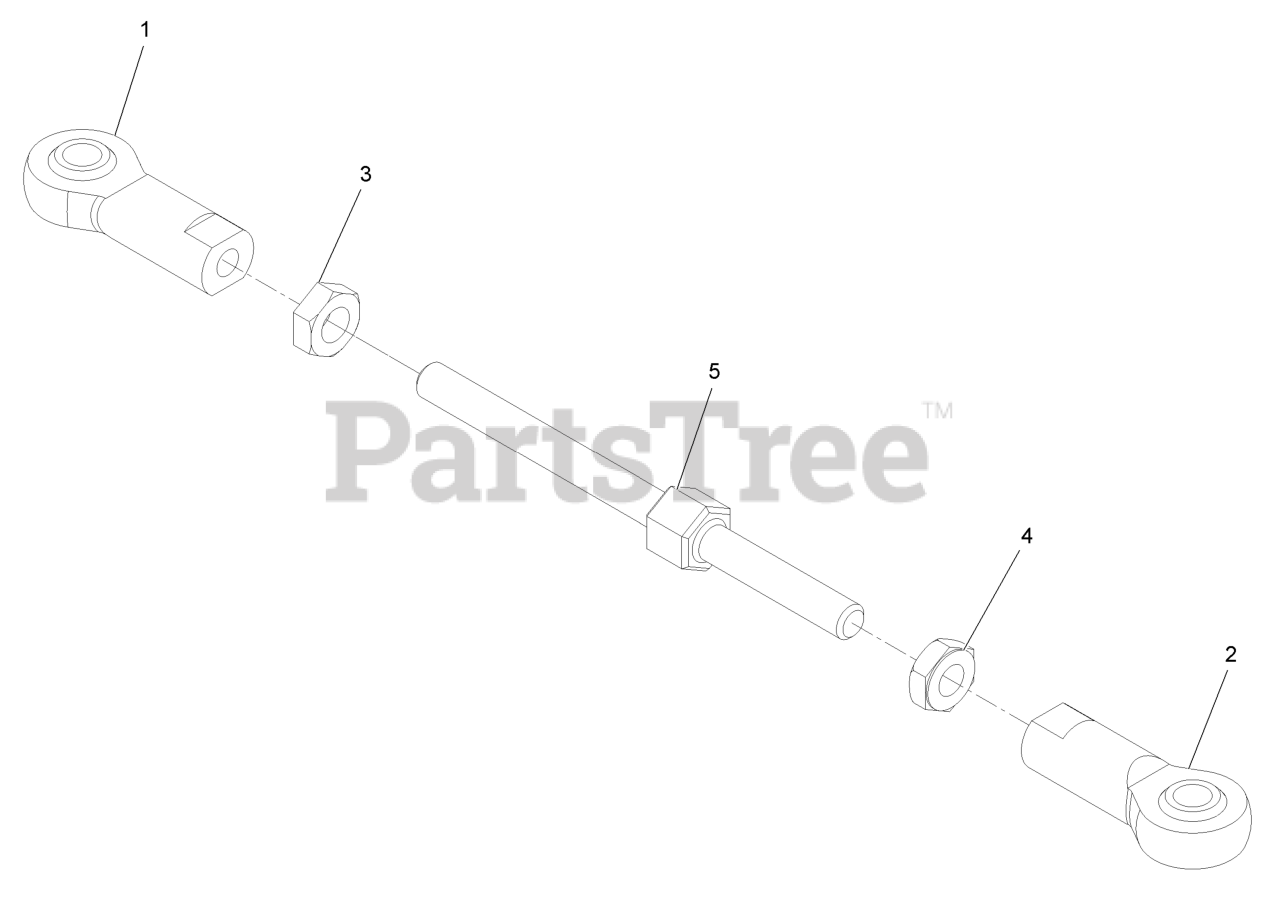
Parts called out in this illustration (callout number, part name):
1	ROD END-BALL JOINT
2	JOINT-BALL, LH
3	NUT-JAM
4	NUT-JAM
5	ROD-VERTICAL ADJUST
